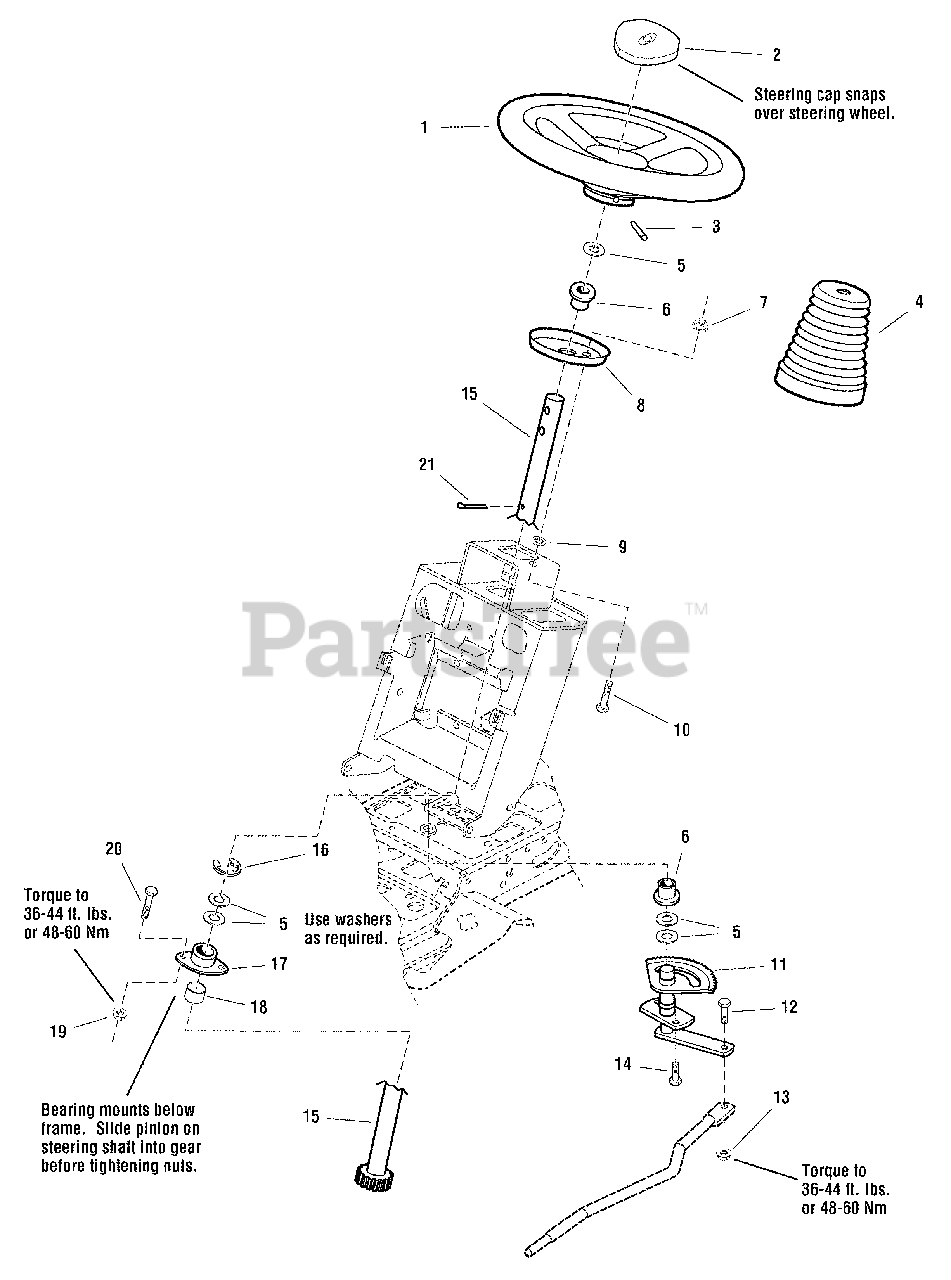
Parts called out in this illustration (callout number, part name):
1	STEERING WHEEL, Straight, Shaft
2	CAP, Steering Wheel
3	PIN, Spring, 5/16 x 2-1/2
4	COVER, Rubber, Upper Steering Shaft
5	WASHER, 3/4
6	BUSHING, 15/32 x 7/8 x 7/8, Nylon
7	NUT, Hex KEPS 1/4-20
8	PLATE, Mounting Steering
9	NUT, Push
10	CARRIAGE BOLT, 1/4-20 x 1-1/4
11	GEAR & SHAFT ASSEMBLY, Steering
12	SCREW, Hex Head, 3/8-16 x 1 1/4
13	NUT, Hex Flange Two-Way Lock, 3/8-16
14	CAPSCREW, Hex Washer Head Taptite, 5/16-18 x 3/4
15	SHAFT & PINION ASSEMBLY, Steering Manual
16	RING, Clipring Extension
17	BEARING, 3/4 x 1-11/16 x 13/16, 3" Long Housing
18	SPACER, 3/4 x 1-1/16 x 3/8, Powder Metal
19	NUT, Hex Flange Whiz Lock, 3/8-16, Small
20	CAPSCREW, Hex Whiz Lock Flange, 3/8-16 x 3/4, Black
21	PIN, Cotter, 1-1/4, Black
